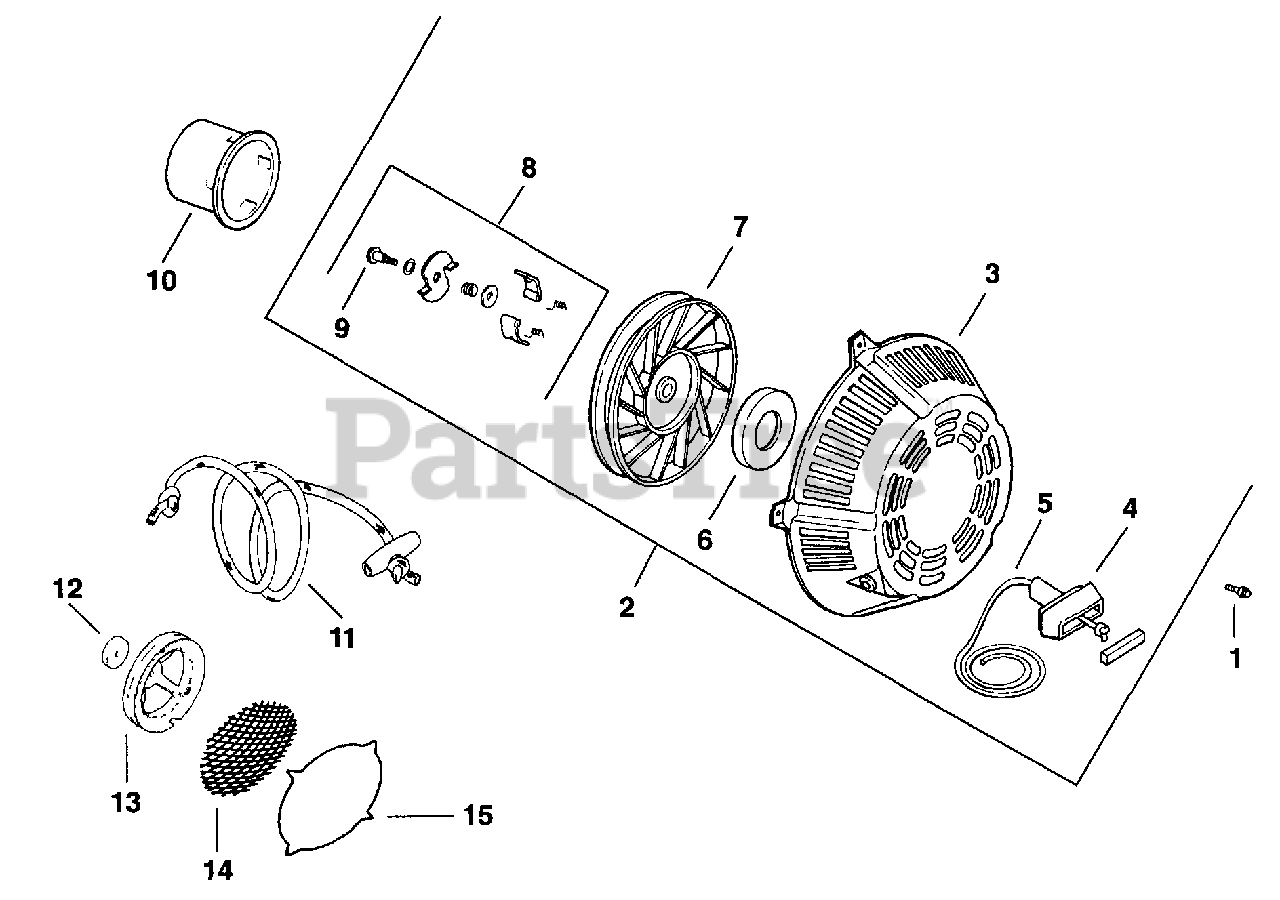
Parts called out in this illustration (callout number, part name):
1	SCREW - USE M-545010
2	STARTER ASSY,RETRACTABLE-USE 12 165 03-S
3	HOUSING - DISCONTINUED
4	HANDLE - USE 25 166 01
5	ROPE - DISCONTINUED
6	SPRING & KEEPER - (#DSC)
7	PULLEY - (#DSC)
8	KIT, DOG REPAIR - (#DSC)
9	SCREW - DISCONTINUED
5235701-S	Lubricant, Inertia Drive Starter (0.25 oz.)
